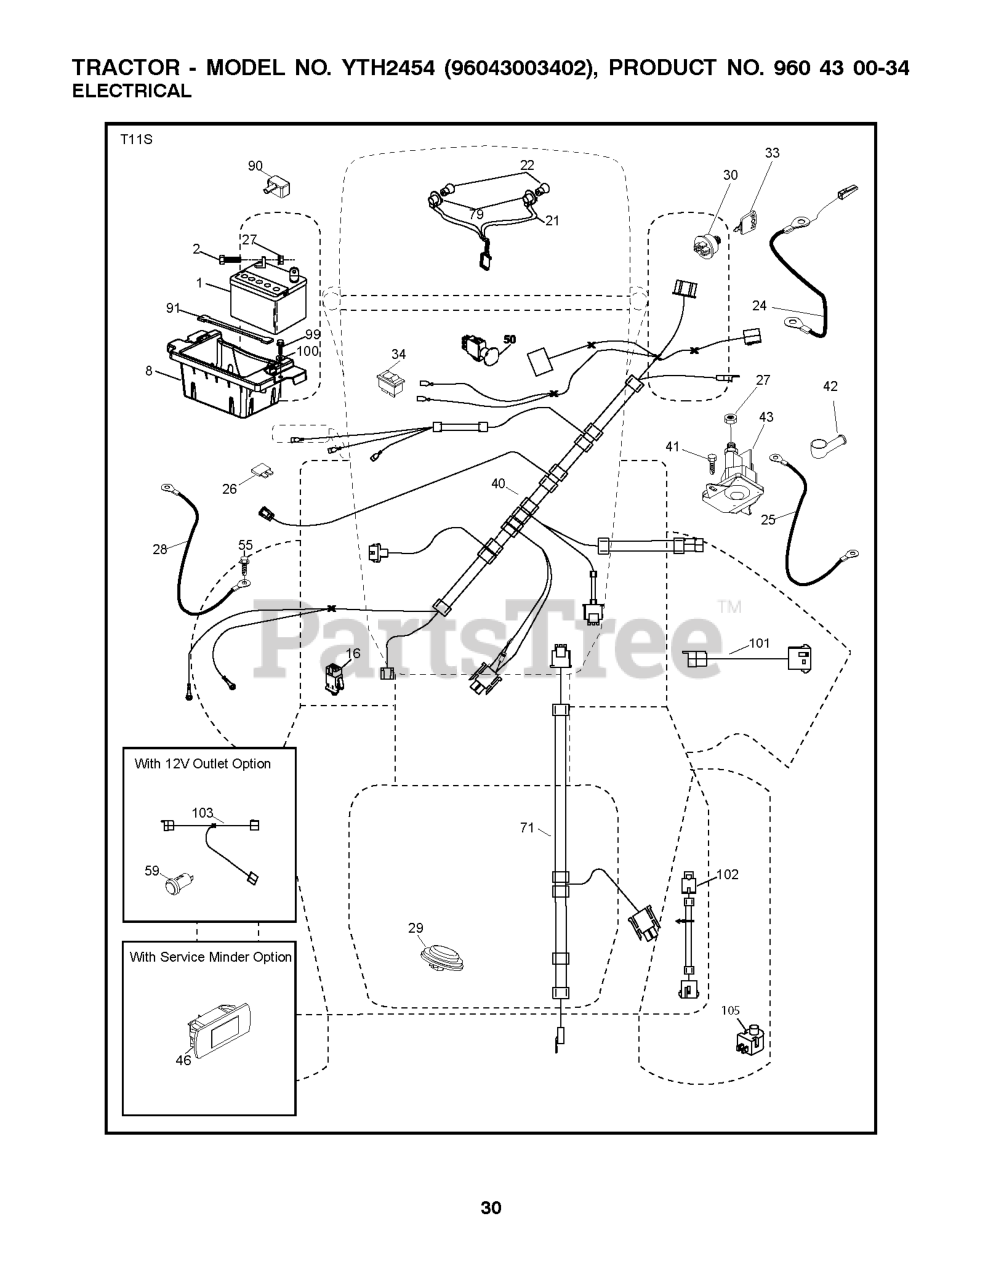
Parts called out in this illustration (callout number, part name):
1	BATTERY 12V .35 AMP
2	BOLT.HEX.1/4.X.3/4.DICHROMATE
8	BOX.BATTERY.MOUNT.FRONT.LT
16	SWITCH INTERLOOK PUSH-IN
21	HARNESS ASSY LIGHT
24	CABLE.BATT.POS.WIRE.TG.DA SOL
25	CABLE.STARTER.6G.BL/RED.17.5
26	FUSE 20AMP
27	NUT
28	CABLE GROUND 6 GA 21" 90T BLK
29	SWITCH.SEAT.DELTA.OPC.
30	SWITCH.IGN.DELTA.W.LGH.ROS
33	KEY.CHAIN.BLISTER.PACK.GEN.INT
40	HARNESS.IGN.DASH.HUQ/P
41	SCREW
42	TERMINAL COVER
43	SOLENOID.W/BRASS.PLUNGER
46	RP.GUAGE.SRVCMNDR.HRMTR.
50	RP.PTO.SWITCH.8 TERMINAL.BLACK
55	SCREW.THDROL.5/16-18X3/4.TTY
59	OUTLET.12-VOLT
71	HARNESS-CHASSIS SUB
79	BULB HOLDER ASM.
90	COVER.TERMINAL.BATTERY
91	STRAP.BATTERY.MOUNT.FRONT(2 2)
99	SCREW HEXWSHR 1/4-20X3/4
101	PIGTAIL.MATNLK.NEW.HAR
102	HARNESS PIGTAIL PCH TEX ROS
103	HARNESS PIGTAIL 12V OUTLET
105	REVERSE SWITCH
